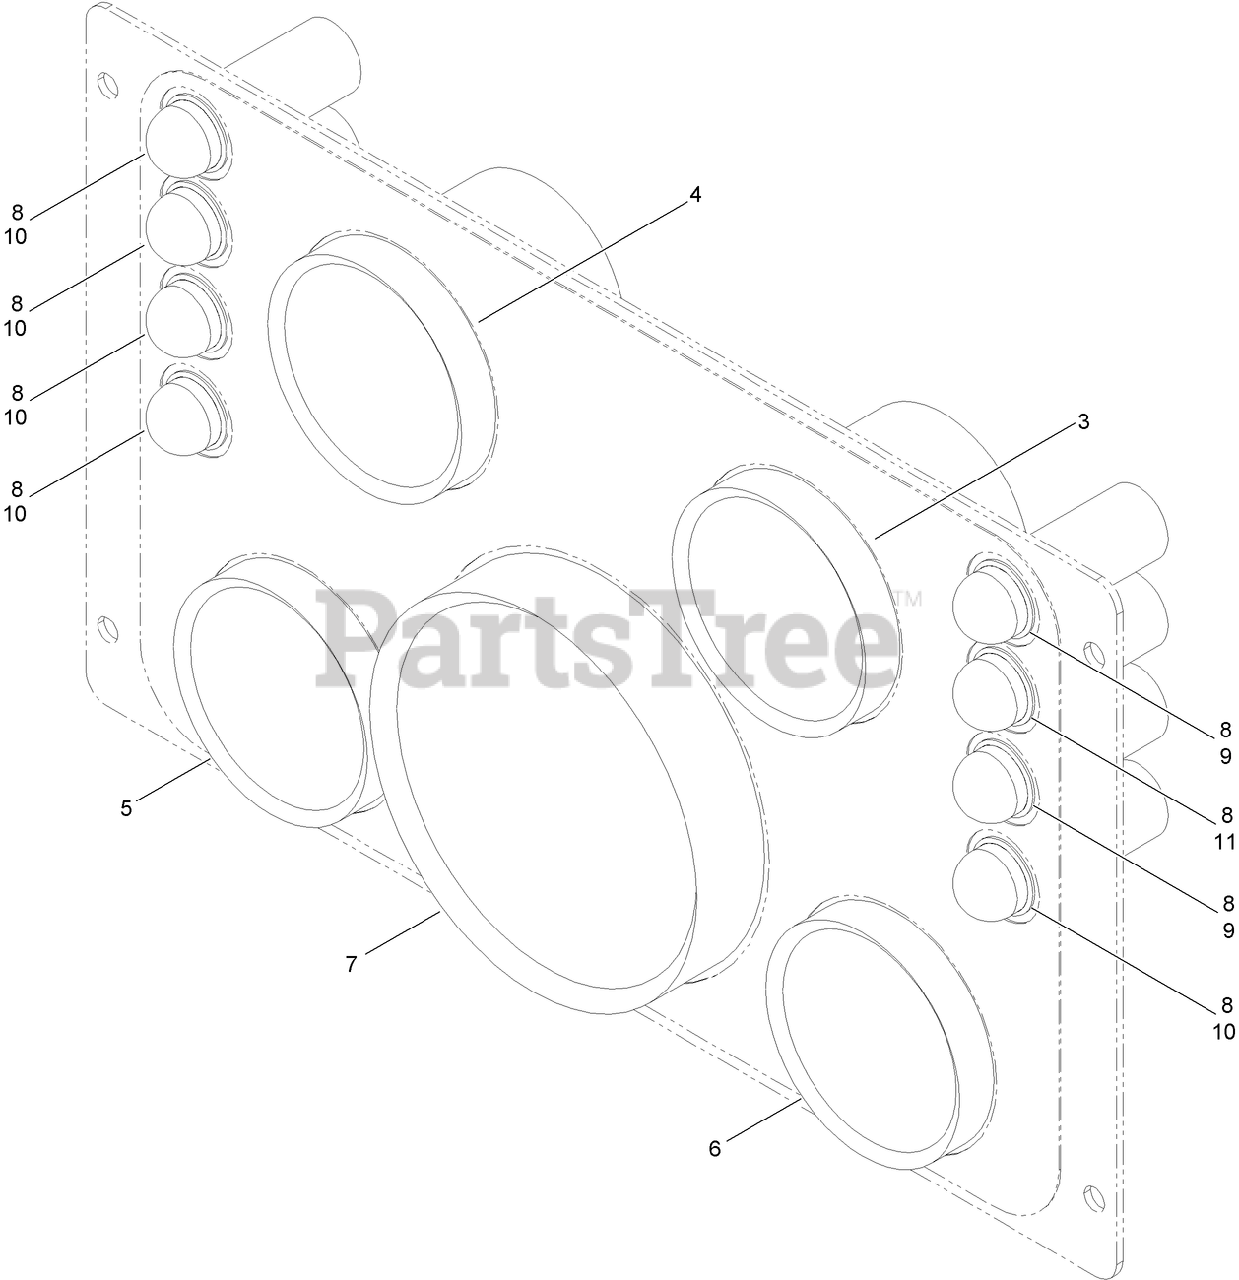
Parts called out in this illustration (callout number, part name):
3	GAUGE-FUEL
4	GAUGE-Volts
5	GAUGE-TEMP
6	GAUGE-HYD OIL TEMP
7	GAUGE-Tachometer
8	BULB-12 Volt
9	LENS-DOME, FLUTED RED (TYPE T-2)
10	LENS-DOME, FLUTED AMBER (TYPE T2)
11	LENS-DOME, FLUTED GREEN (TYPE T2)
